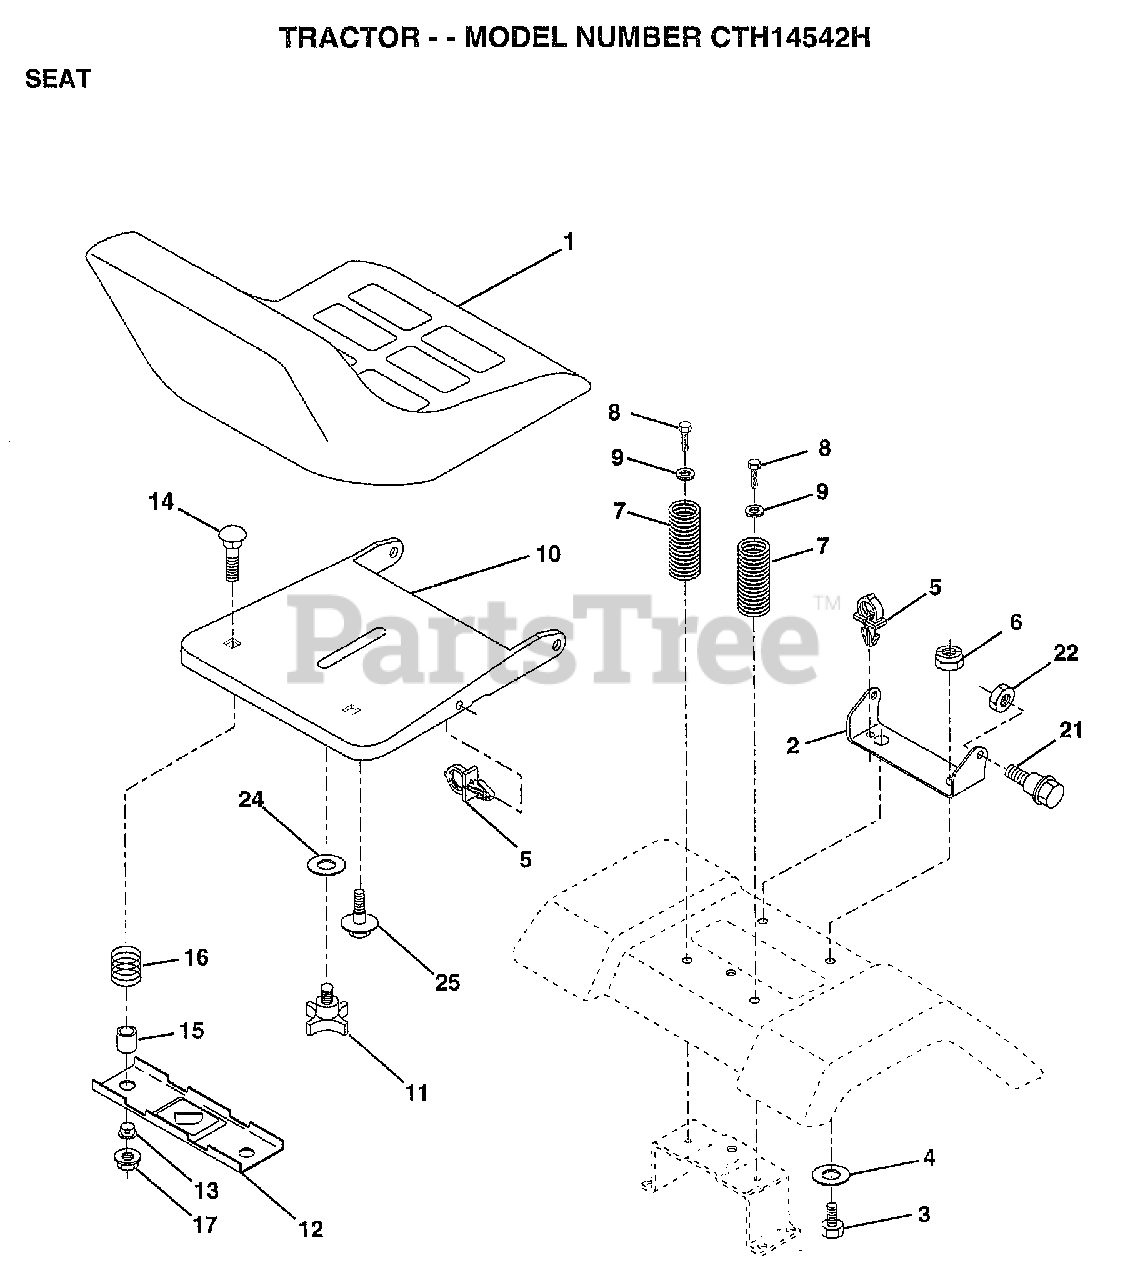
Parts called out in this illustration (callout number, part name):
2	BRACKET PVT SEAT
3	BOLT
4	WASHER PM
5	CLIP.PUSH-IN.HING
6	NUT
7	SPRING COMPRESSIO
8	SCREW GTV
9	WASHER
10	PAN-SEAT
11	"KNOB 1/2"" YT"
12	BRKT SWITCH
13	BUSHING
14	BOLT-RD HD SQ NK
15	SPACER SPLIT
16	SPRING COMPRESSED
21	"BOLT,SHOULDER"
24	WASHER
25	"BOLT,SHOULDER"
